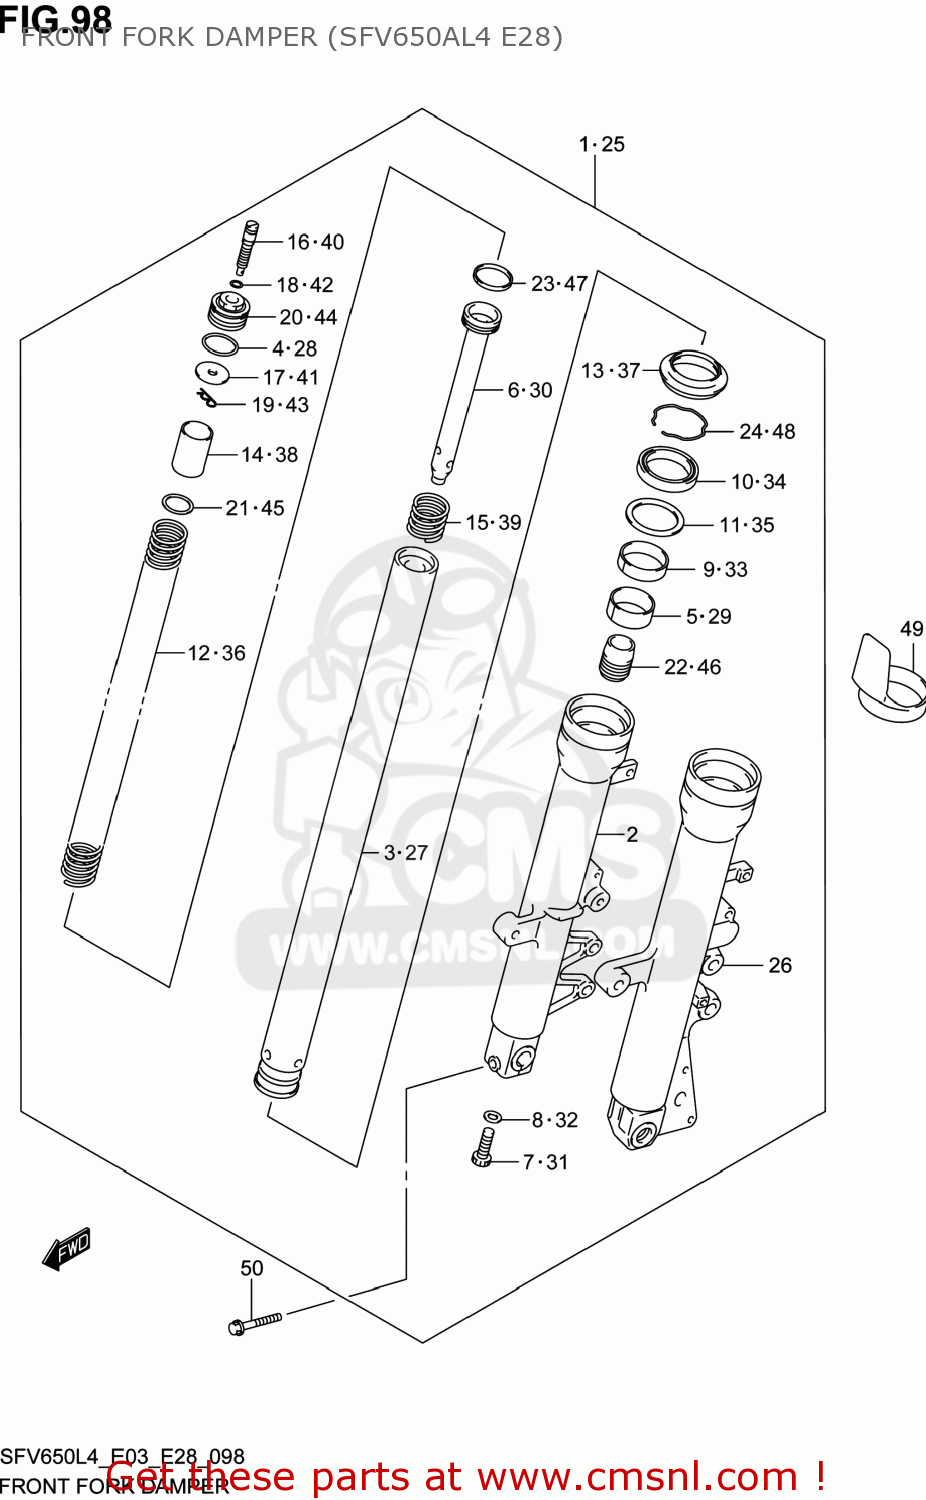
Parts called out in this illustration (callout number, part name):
1	DAMPER ASSY,FR FORK,R
2	TUBE,OUTER,R
3	TUBE,INNER
4	O RING
5	BUSH,SLIDE
6	CYLINDER
7	BOLT(8X27)
8	GASKET (NAS)
9	BUSH,GUIDE
10	SEAL,OIL
11	SPACER,SEAL
12	SPRING,FR
13	SEAL,DUST
14	COLLAR,SPRING(32.9X34X50)
15	SPRING,REBOUND
16	ADJUSTER BOLT,SPRING
17	SEAT,SPRING
18	O RING(D:1.9,ID:8.6)
19	PIN,SEAT SPRING
20	BOLT,FORK
21	JOINT,SPRING
22	PIECE,OIL LOCK
23	RING,PISTON
24	CIRCLIP,FORK OIL SEAL
25	DAMPER ASSY,FR FORK,L
26	TUBE,OUTER,L
27	TUBE,INNER
28	O RING
29	BUSH,SLIDE
30	CYLINDER
31	BOLT(8X27)
32	GASKET (NAS)
33	BUSH,GUIDE
34	SEAL,OIL
35	SPACER,SEAL
36	SPRING,FR
37	SEAL,DUST
38	COLLAR,SPRING(32.9X34X50)
39	SPRING,REBOUND
40	ADJUSTER BOLT,SPRING
41	SEAT,SPRING
42	O RING(D:1.9,ID:8.6)
43	PIN,SEAT SPRING
44	BOLT,FORK
45	JOINT,SPRING
46	PIECE,OIL LOCK
47	RING,PISTON
48	CIRCLIP,FORK OIL SEAL
49	PROTECTOR
50	BOLT
